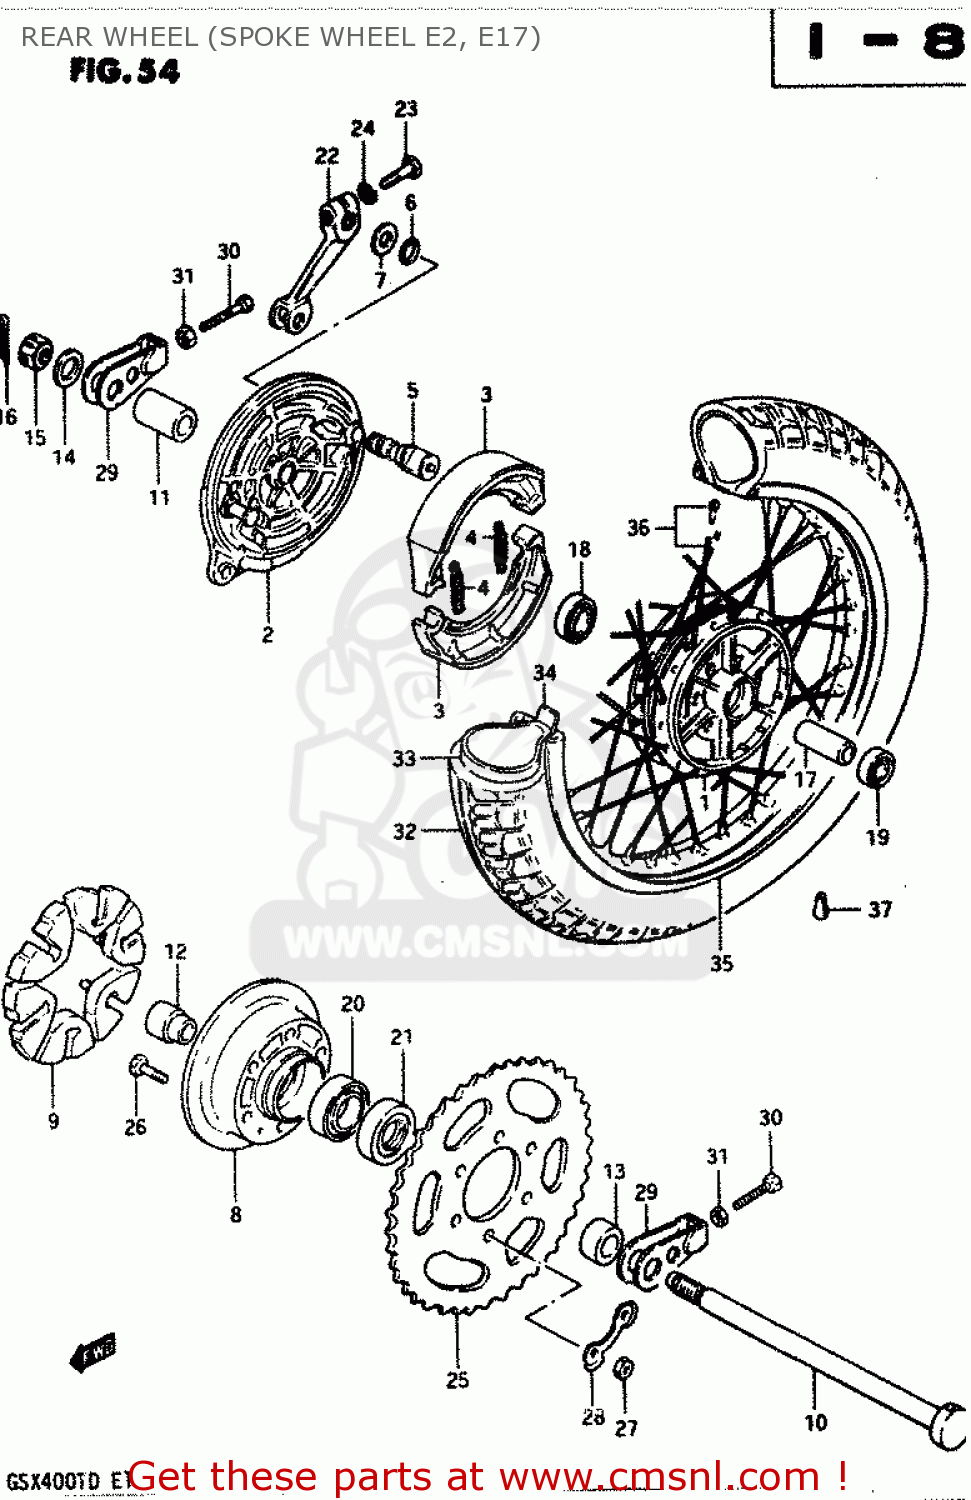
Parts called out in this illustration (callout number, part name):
1	DRUM,REAR HUB
2	PANEL,REAR HUB
3	SHOE,BRAKE
4	SPRING,BRAKE SHOE
5	CAM,FRONT BRAKE
6	O-RING,BOSS
7	WASHER (15X24X1.6)
8	DRUM,REAR SPROCKET MOUNT
9	ABSORBER,RR HUB SHOCK
10	AXLE,REAR
11	SPACER(17.5X28X44.8)
12	SPACER,REAR HUB BEARING
13	SPACER(17X30.5X22.3)
14	WASHER (17X30X3.2)
15	NUT
16	PIN,COTTER
17	SPACER (17.6X24X57)
18	BEARING
19	BEARING
20	BEARING
21	SEAL,OIL(30.5X52X8)
22	LEVER,RR BRAKE CAM
23	BOLT
24	LOCK WASHER
25	SPROCKET,REAR (NT:43)
26	BOLT
27	NUT
28	WASHER
29	ADJUSTER,CHAIN
30	BOLT 8X50
31	NUT
32	TIRE
33	TUBE ASSEMBLY,WHEEL,INNER
34	PROTECTOR,WHEEL,INNER
35	RIM,REAR WHEEL
36	SPOKE ASSY,RR
37	BALANCER,WHEEL (B)
